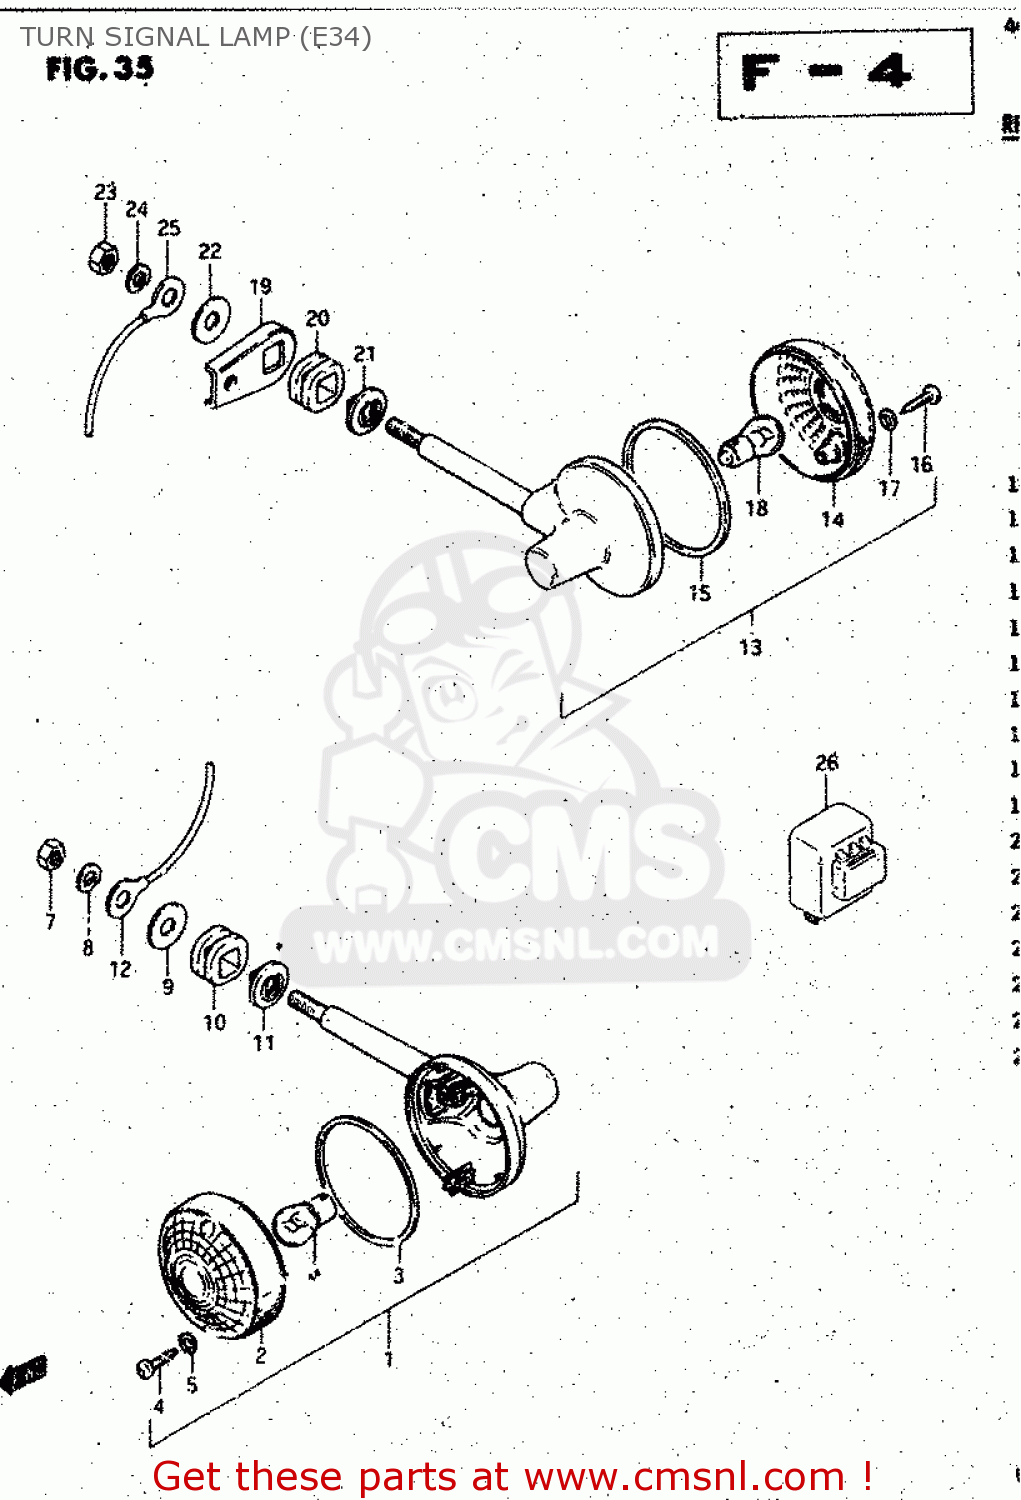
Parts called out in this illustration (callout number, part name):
1	LAMP ASSY, FRONT TURN SIGNAL
2	LENS
3	GASKET (NAS)
4	SCREW
5	GASKET (NAS)
6	BULB(12V21W)
7	NUT
8	LOCK WASHER
9	WASHER (10.5X30X2.3)
10	CUSHION
11	SPACER
12	LEAD WIRE,EARTH
13	LAMP ASSY, REAR TURN SIGNAL
14	LENS,TURN SIGN
15	GASKET (NAS)
16	SCREW
17	GASKET (NAS)
18	BULB(12V21W)
19	BRACKET,RR TURNSIGNAL LAMP
20	CUSHION
21	SPACER
22	WASHER (10.5X30X2.3)
23	NUT
24	WASHER,LOCK,10
25	LEAD WIRE,EARTH
26	RELAY ASSEMBLY,TURN SIGNAL
